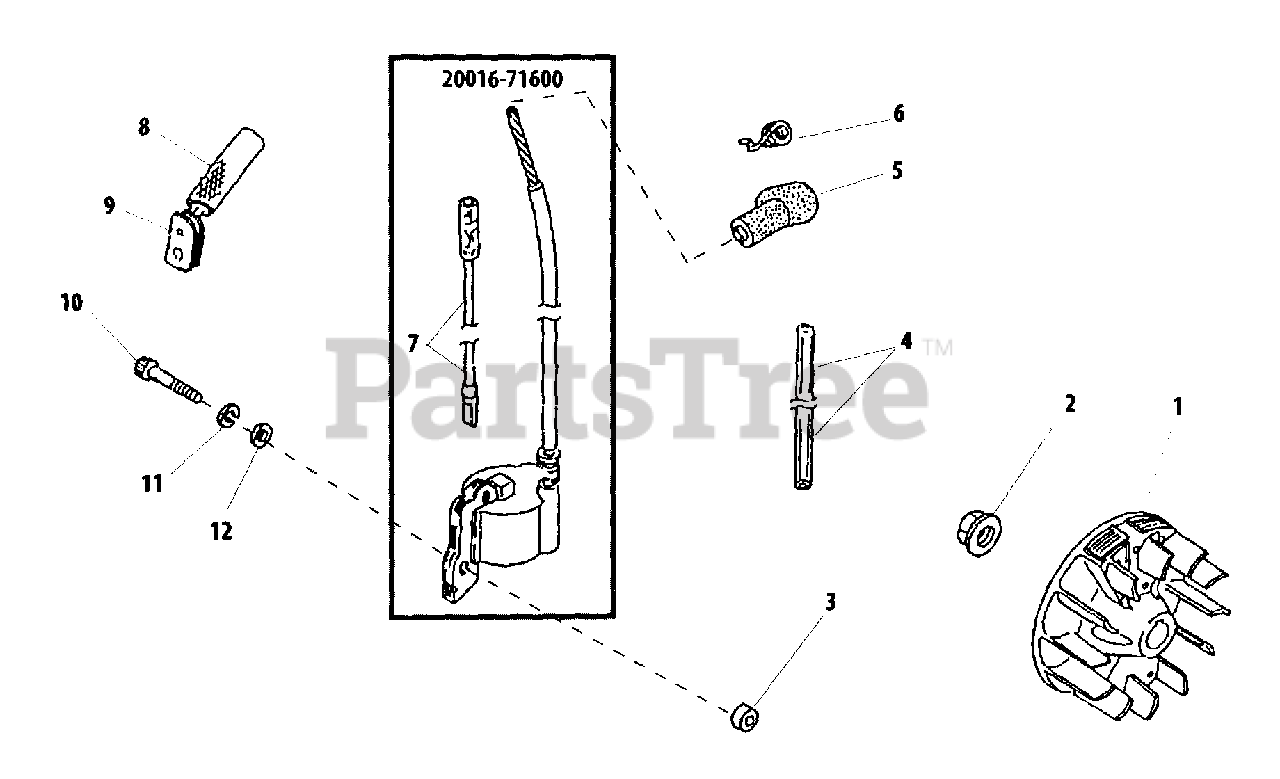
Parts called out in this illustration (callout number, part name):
1	FLYWHEEL
2	NUT M8
3	INSULATOR 4.2×11×6
4	TUBE, INSULATOR
5	CAP, SPARK PLUG
6	TERMINAL, SPARK PLUG
7	WIRE
8	TUBE, IGNITION COIL
9	GROMMET
10	BOLT
11	WASHER, SPRING 4 MM
12	WASHER 4 MM
20016-71600	IGNITION COIL ASSY
